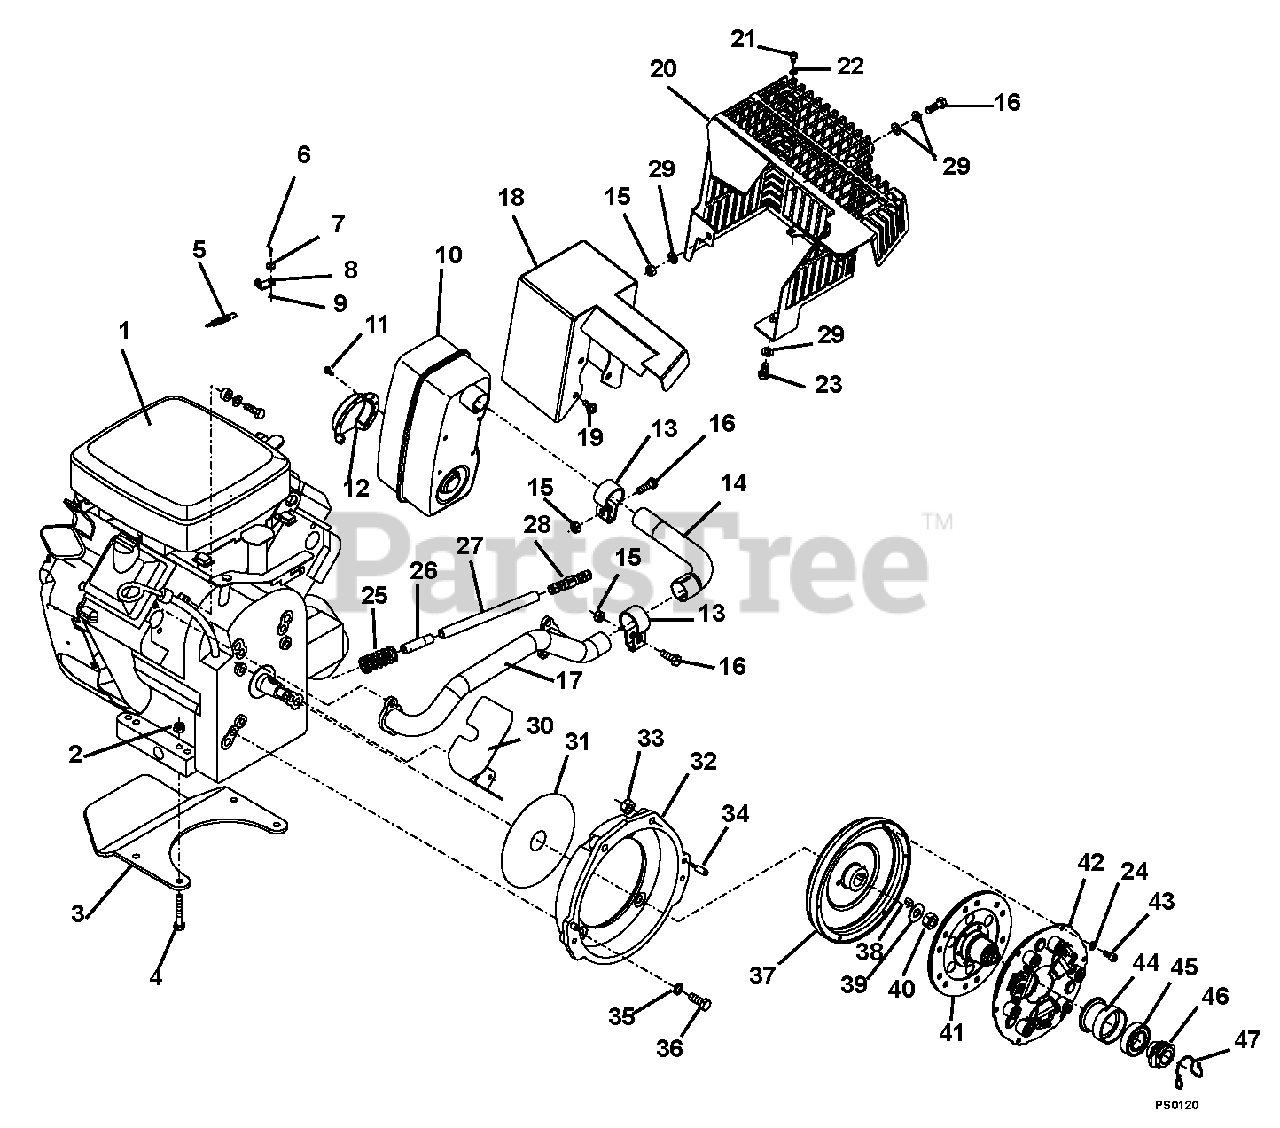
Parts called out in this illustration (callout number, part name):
2	Nut, Lock, D985 Metric 8
3	Plate, Guard
4	Bolt, Hex D931 Metric 8 x 45
5	Spring, Tension D912 Metric 2 x 10
9	Hex Nut, D934-Metric 2
10	Silencer
12	Deflector
14	Exhaust Pipe
15	Nut, Hex D934 M8
16	Bolt, Hex, D933 Metric 8 x 25
17	Manifold
18	Heat Protector
19	Screw, D7500D M6 x 16
20	Heat Protector
21	Screw, D912 Metric 5 x 8
22	Washer, M5
23	Bolt, Hex, D933 Metric 8 x 16
24	Pressure Spring, 3,2/20 x 49,5
25	Ventilation Valve
26	Hose, 904001 LW 10 x 14
27	Nipple, Reduction, D1=12
28	Adjustment Ring, D705A 8-H8
29	Washer, M8
30	Heat Protector
31	Plate, Intermediate
32	Engine, Flange
33	Nut, Lock, D934 M10
34	Pin, Straight, BN 855 8-H8 x 20
35	Washer, FORM Z 10.2/16.1 x 1.6
36	Bolt, Hex, UNC 3/8" x 1"
37	Flywheel
38	Key, Feather, D6885A 6 x 6 x 16
40	Hex Nut, D934 M12 x 1,25
41	Disk, Clutch
42	Pressure Plate
43	Screw, D912 Metric 6 x 14
44	Ring, Pressure
45	Bearing, Ball, 6005 2RS
46	Pressure Ring
47	Spring, Lock
